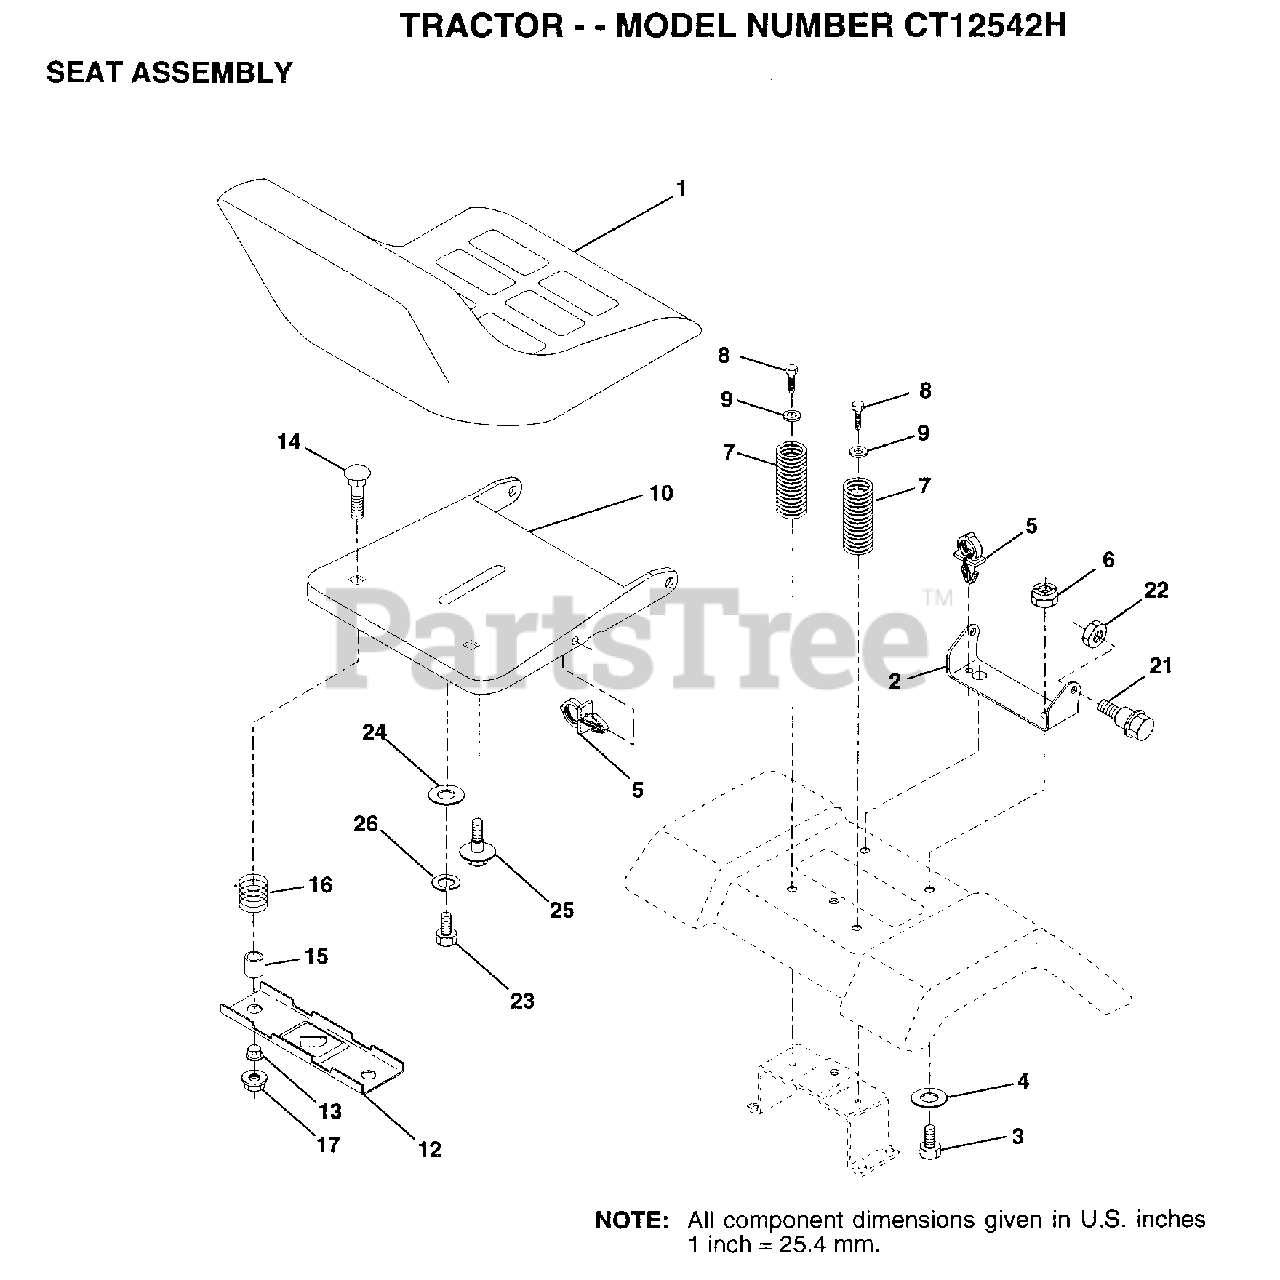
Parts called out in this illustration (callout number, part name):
2	BRACKET PVT SEAT
3	BOLT
4	WASHER PM
5	CLIP.PUSH-IN.HING
6	NUT
7	SPRING COMPRESSIO
8	SCREW GTV
9	WASHER
12	BRKT SWITCH
13	BUSHING
15	SPLIT SPACER
16	SPRING
21	"BOLT,SHOULDER"
22	NUT
23	BOLT
24	WASHER
25	"BOLT,SHOULDER"
26	LOCKWASHER
